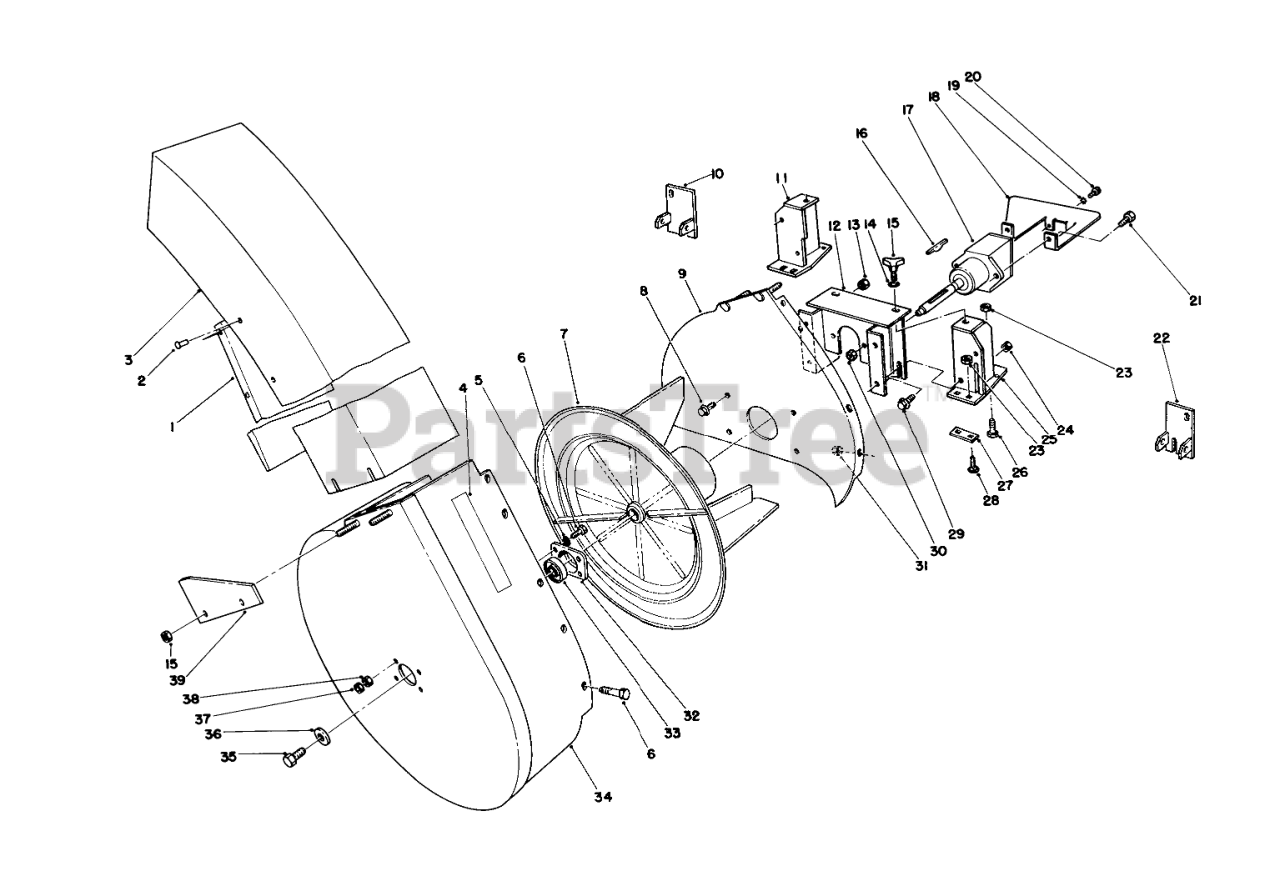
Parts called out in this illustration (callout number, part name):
1	Deflector
3	Chute Assembly (Incl. Ref. #1 & 2)
4	Decal-Waming
5	WASHER-LOCK
6	SCREW-HH
7	Impeller
8	SCREW-HHF
9	Mounting Plate
10	Bracket-Deflector L.H.
11	LH BRACKET ASM
12	Blower Mount
13	NUT-LOCK, NI
14	WASHER-FLAT
15	Knob
17	Asm-Gear Box
18	Cover-Gear Box
19	WASHER-LOCK, EXT
21	SCREW-HH
22	Bracket-Deflector R.H.
23	NUT-LOCK, CONE
24	NUT-JAM
25	RH BRACKET ASM
26	SCREW-HH
27	Plate-Bracket
28	BOLT-CARR
29	SCREW-HHF
30	NUT-LOCK, NI
31	NUT-LOCK, NI
32	CUP-BEARING
33	BEARING-BALL
34	Blower Housing
35	CAPSCREW 3/8 16 3/4
36	SPACER
37	NUT-JAM
38	NUT-HEX
39	Bracket
